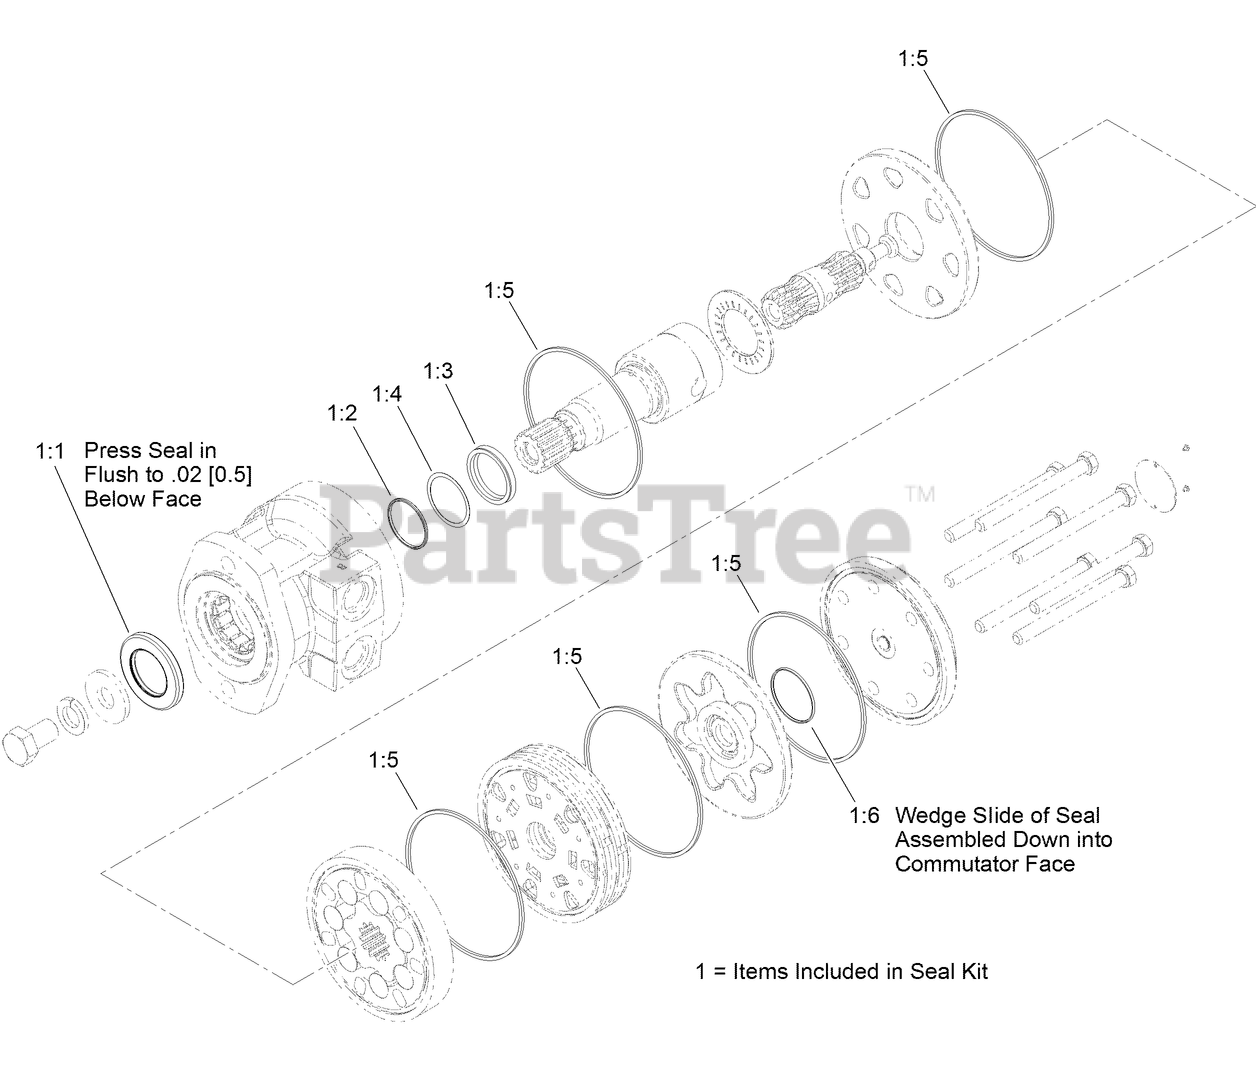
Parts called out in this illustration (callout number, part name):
1	SEAL KIT
1:1	Ring-Back Up
1:2	Washer-Back Up
1:3	SEAL-Shaft
1:4	Deck ASM
1:5	Deck ASM
1:6	Deck ASM
